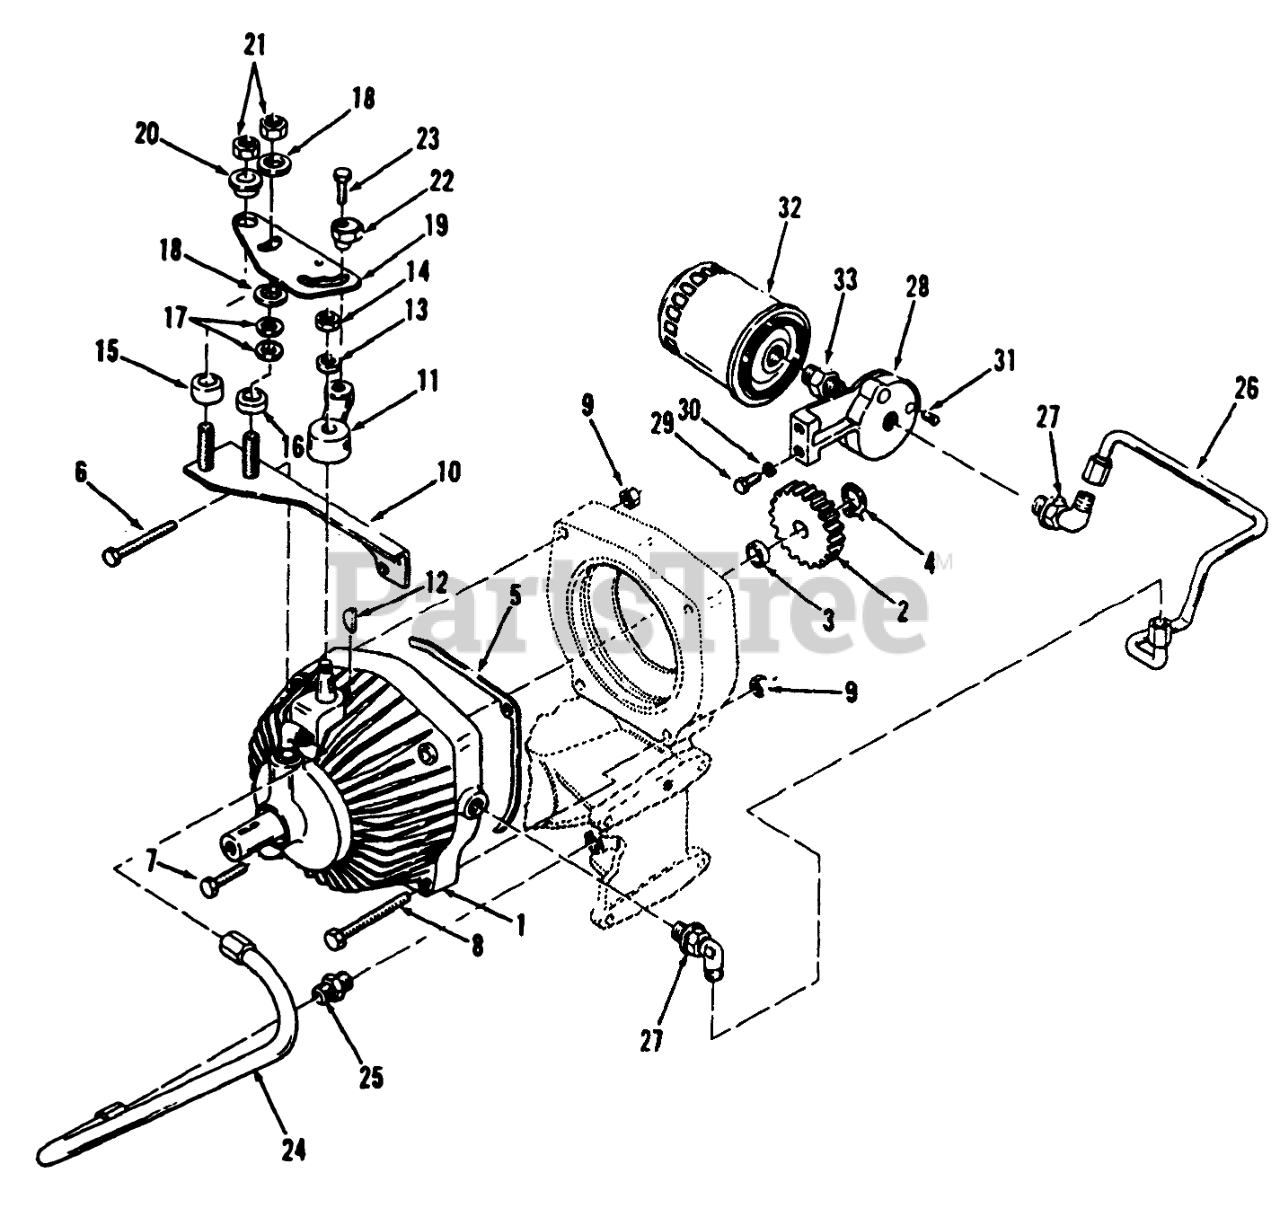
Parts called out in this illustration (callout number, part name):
1	Pump & Motor
2	GEAR 20 TEETH DRIVE
3	SPACER GEAR
4	RING-SNAP, EXTERNAL
5	GASKET
6	SCREW-HH
7	Bolt
8	SCREW-HH
9	NUT-LOCK, NI
10	ASSY-PLATE B
11	ARM-SPEED CONTROLB
12	KEY-WOODRUFF
13	NUT-LOCK, NI
14	NUT-LOCK, NI
15	SPACER-PIVOT
16	SPACER-FRICTION
17	WASHER-SPRING DISC
18	FRICTION WASHER
19	CAM-SPEED CONTROL (NS)
20	CAM-SPACER
23	SCREW-HH
24	ASSY-TUBE SUCTION
25	FITTING-TUBE
26	ASM-TUBE FILTER OUTL
27	ELBOW
28	BASE-FILTER
29	SCREW-HH
30	WASHER-LOCK
32	OIL FILTER ASM
33	FITTING
